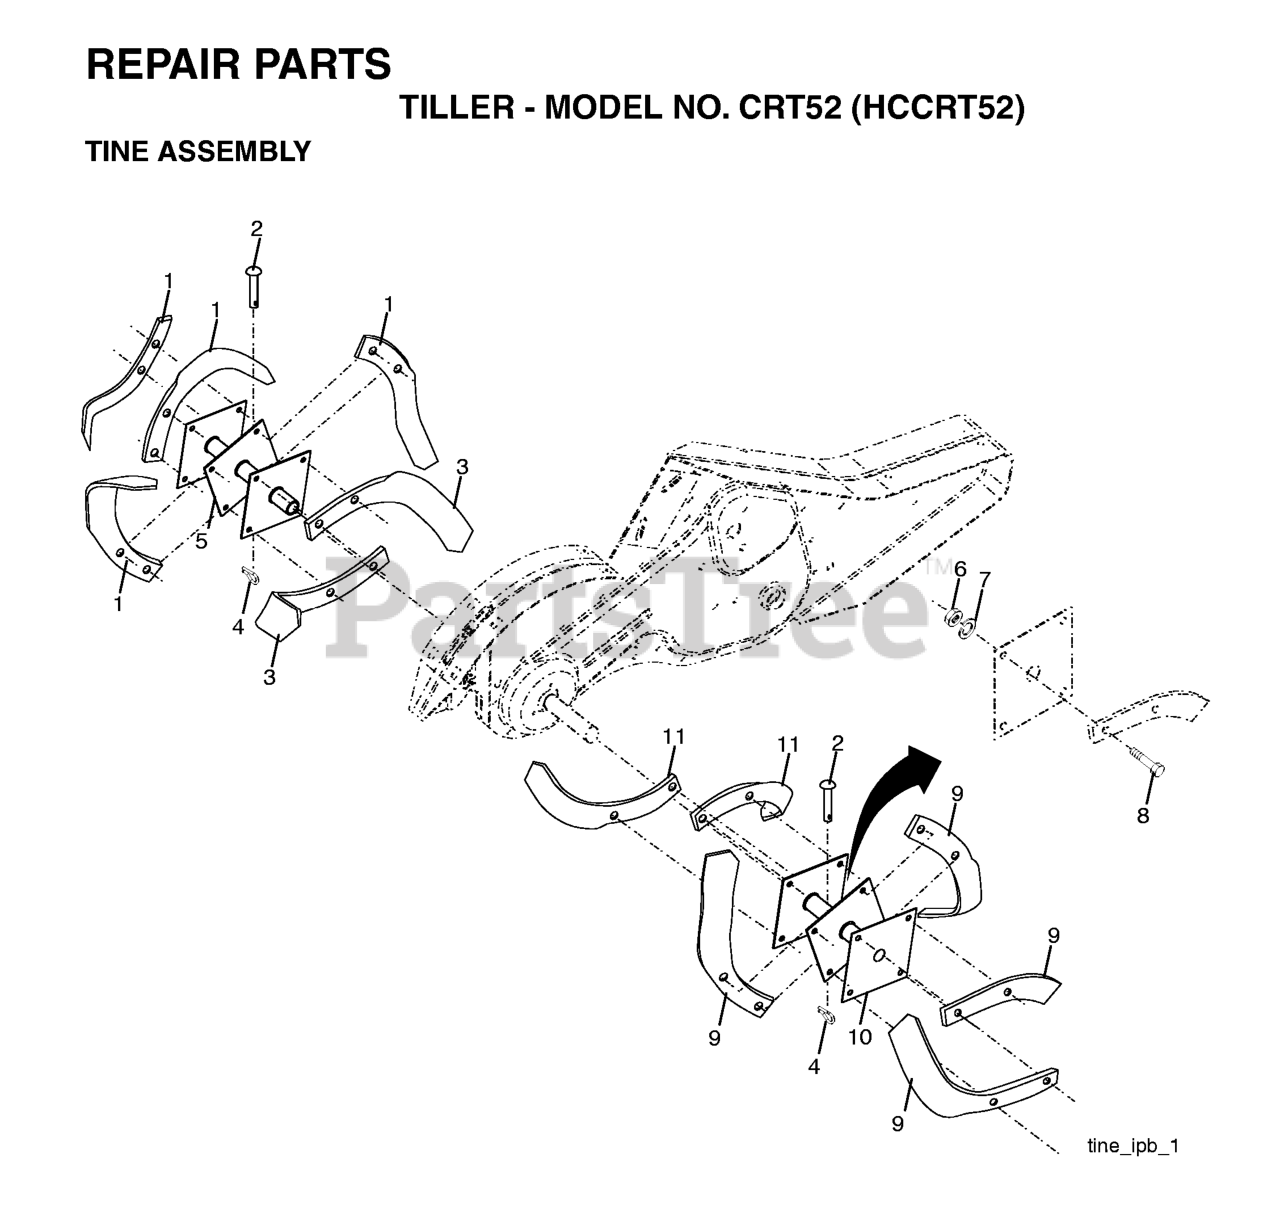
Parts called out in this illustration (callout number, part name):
1	TINE TI
2	PIN RETAINING SCREW
3	TINE.LH.12"(72L)
4	SPRING RETAINER
5	HUB.&.PLATE.ASM.LH
6	NUT
7	WASHER, LOCK 3/8
8	BOLT.HEX.001X20.37-24X1.ZINC
9	TINE TI
10	HUB & PLATE ASM RH
11	TINE.RH.12"(72R)
